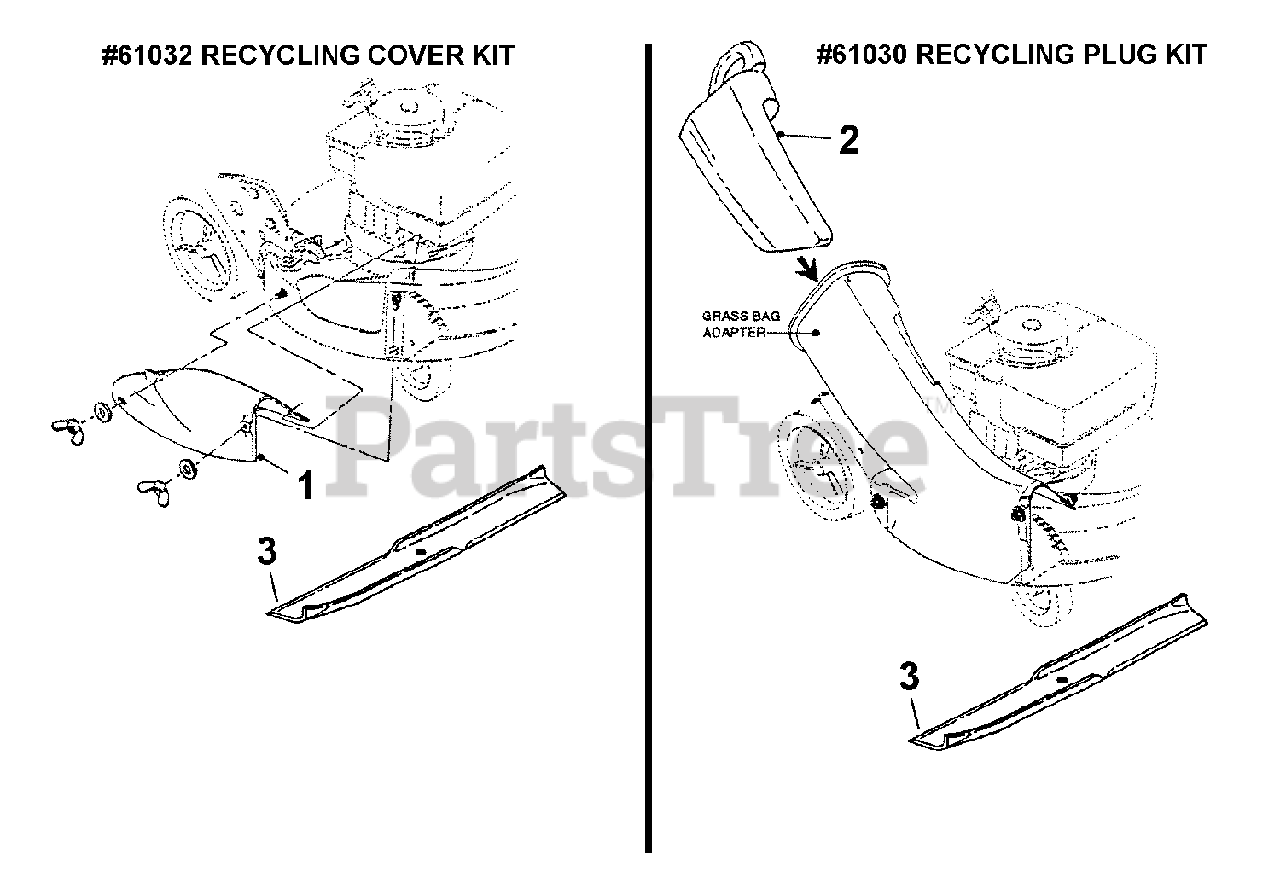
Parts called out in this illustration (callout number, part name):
1	COVER, 21" Deck
2	PLUG, Chute Adapter
3	BLADE, 21"
